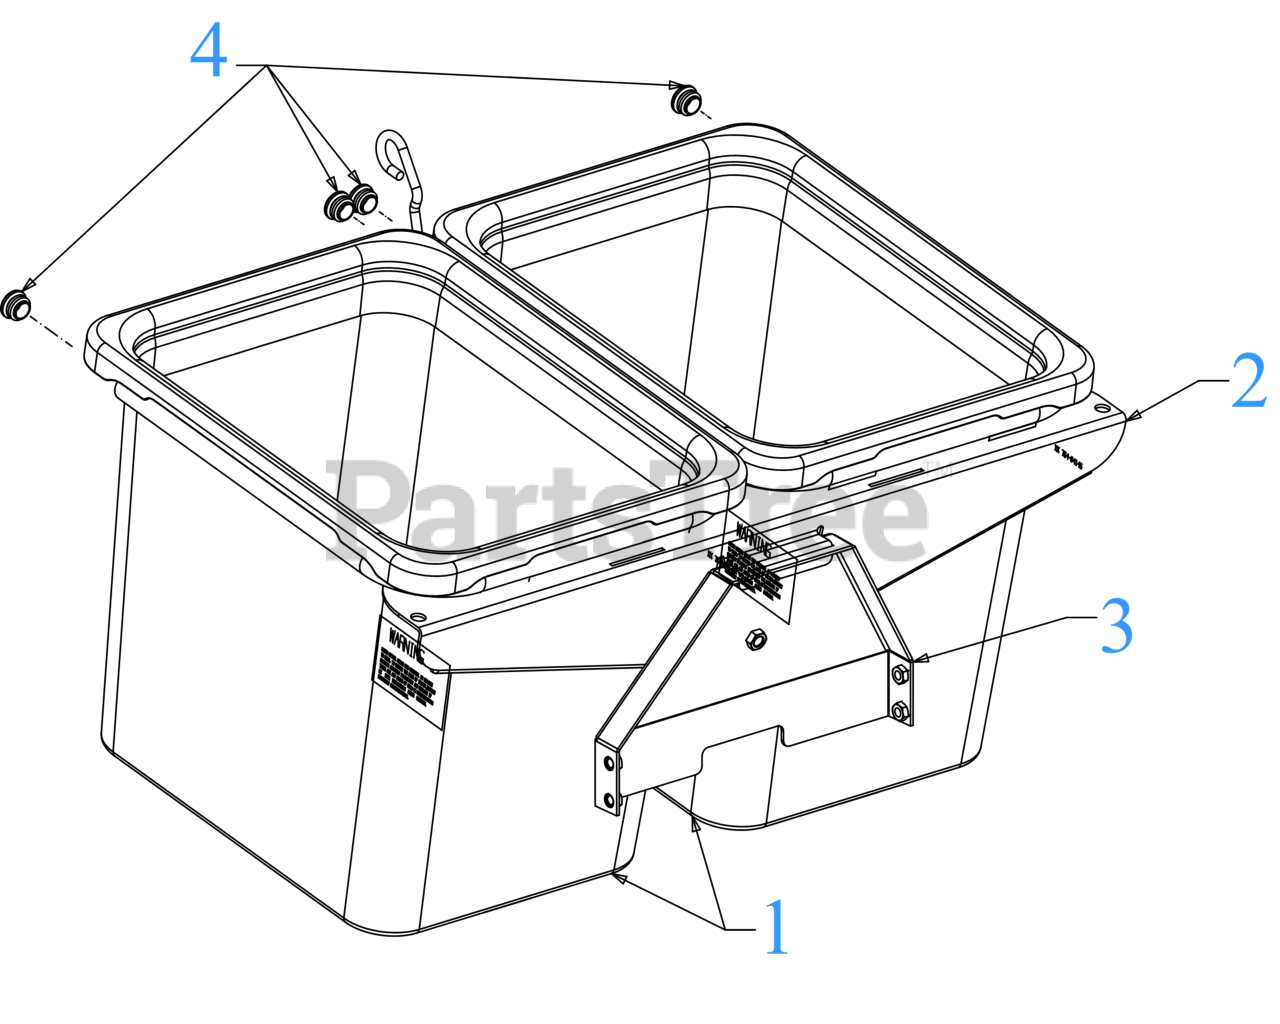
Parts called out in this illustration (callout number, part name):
1	BAG ASSEMBLY
2	SUPPORT ASSEMBLY (POWDER BLACK)
3	BAG SUPPORT BRACKET
